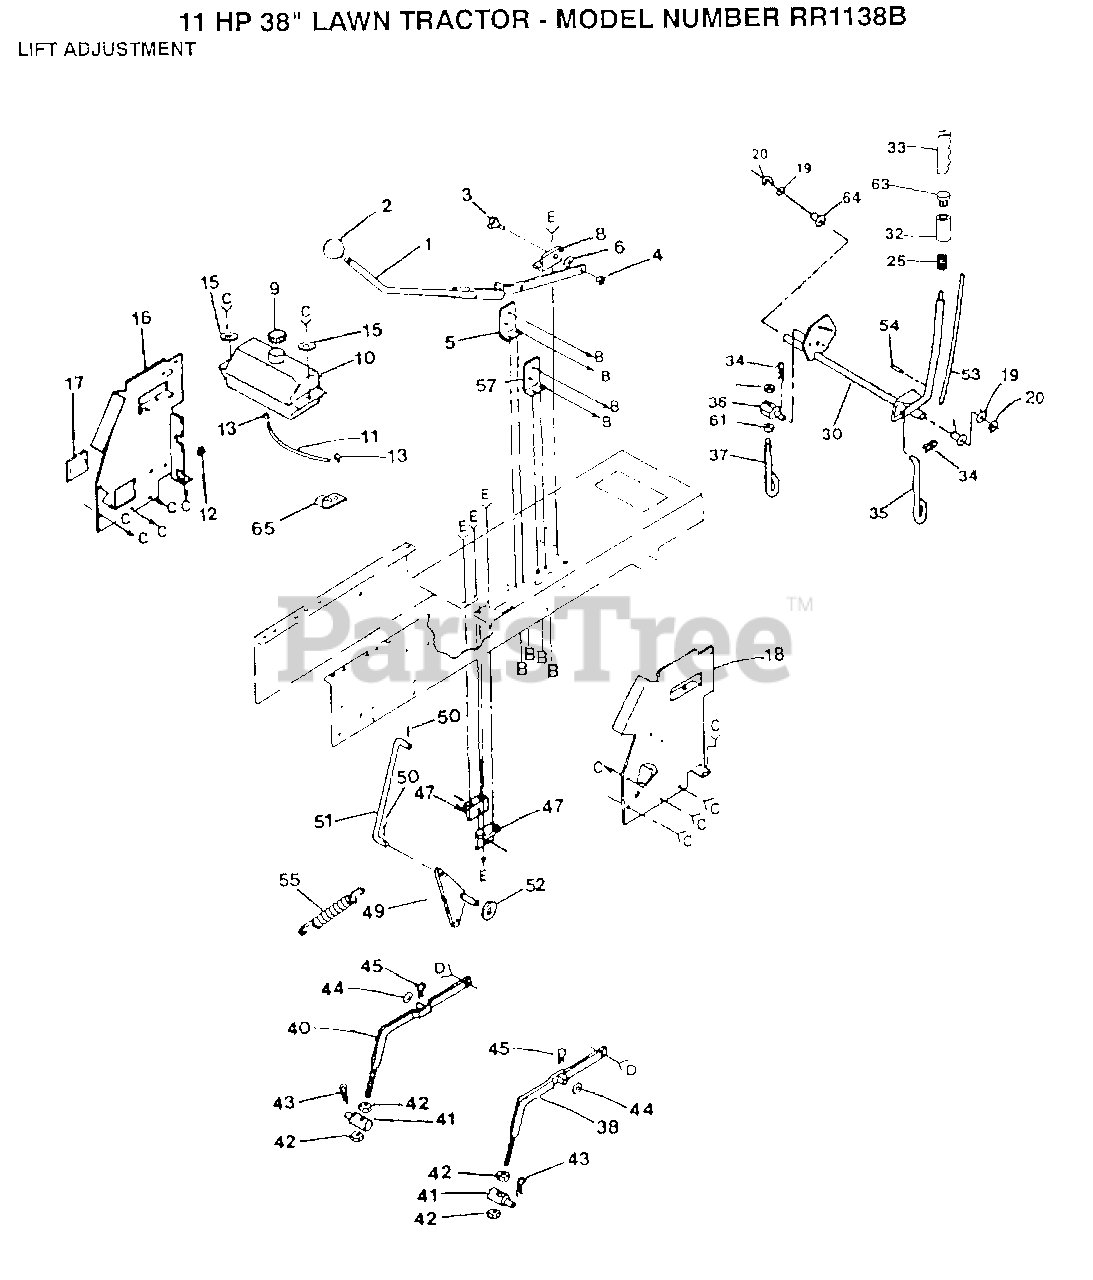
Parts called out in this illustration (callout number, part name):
2	KNOB T(3/8 HOLE)
3	"BOLT, SHOULDER LT"
5	"BRACKET,SWITCH LT"
7	SCREW
8	"SUP,LVR,CLUTCH LT"
10	TANK.FUEL.LT.
11	FUEL LINE T
12	SNAP BUSHING T
13	HOSE CLAMP
14	SCREW
15	WASHER GT
16	PANEL DASH LH
17	COVER ACCESS
19	WASHER
33	GRIP
35	LIFT LINK LT
37	PIVOT PIN T
38	RH SUSP ARM ASM
39	"BOLT, SHOULDER LT"
40	LH SUSP ARM ASM
42	NUT
43	SPRING H
45	SPRING.RETAINER
47	"BRKT,BELLCRAN T"
49	"T, BELLCRANK"
50	COTTER PIN
52	WASHER
54	PIN-GROOVE LT
57	BRACKET LT
59	WASHER T
60	NUT SPECIAL T
61	NUT
64	NYLON BEARING
65	INSUL CLIP T
